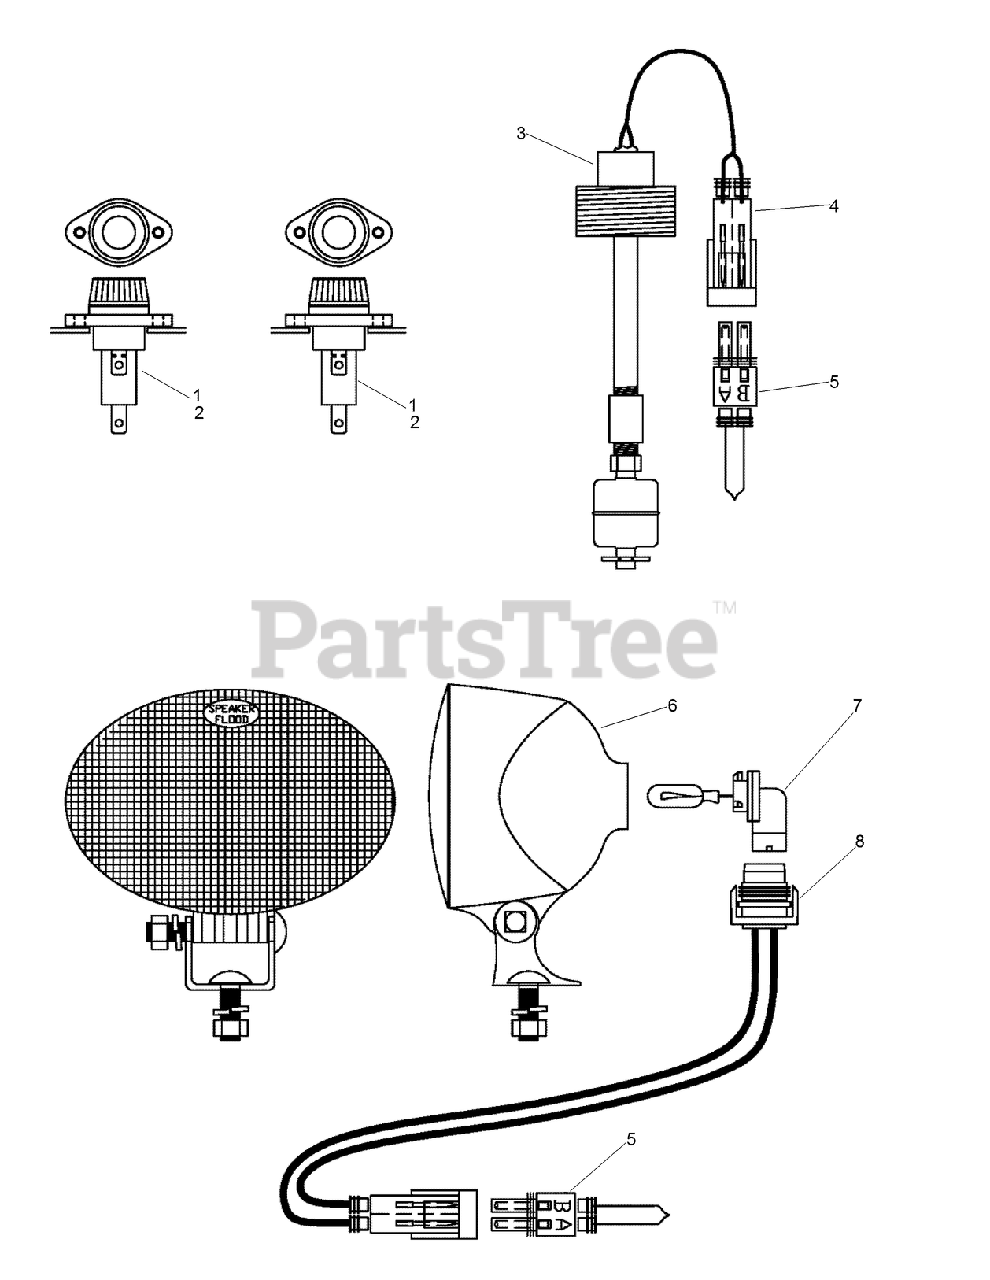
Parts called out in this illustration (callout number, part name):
1	HOLDER - Fuse
2	FUSE - Miget, 250 VDC, 30A
3	SWITCH - False
4	CONNECTOR ASSEMBLY - 2 Pin
5	CONNECTOR ASSEMBLY - 2 Socket
6	ASSEMBLY - Flood Light, 12 VDC, Oval
7	BULB - 886
